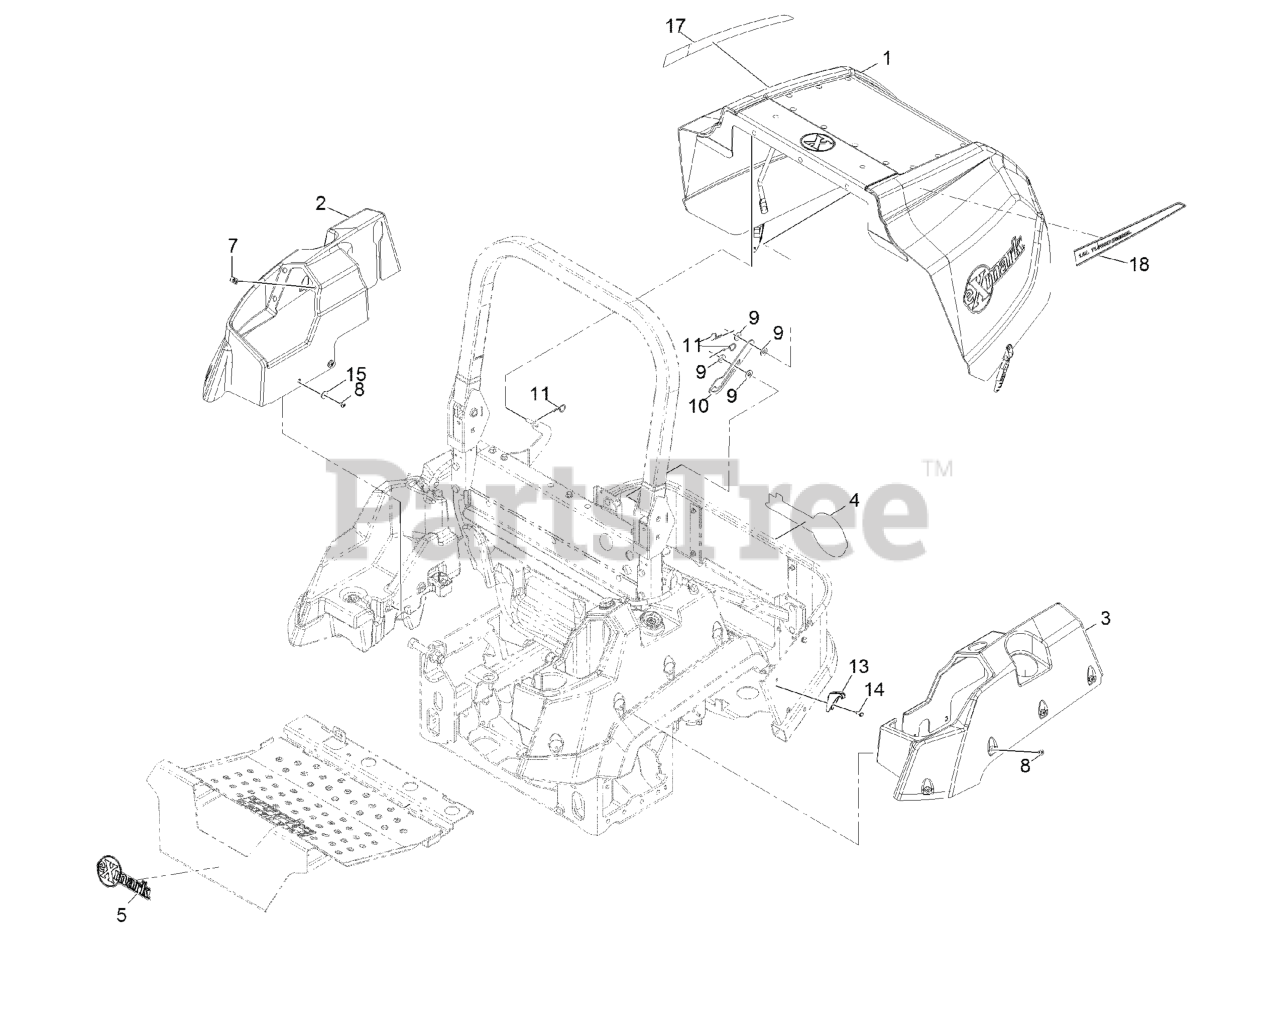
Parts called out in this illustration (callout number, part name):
1	Hood ASM
2	COVER-TANK, RH
3	COVER-TANK, LH
4	DECAL-EXMARK
5	DECAL-EXMARK
8	SCREW-TORX
9	WASHER-FLAT
10	PROP-HOOD
11	PIN-COTTER, HAIR
13	LATCH-CATCH
14	SCREW-HWH
15	WASHER-FLAT
17	DECAL-TURBO DIESEL-RH
18	DECAL-TURBO DIESEL-LH
